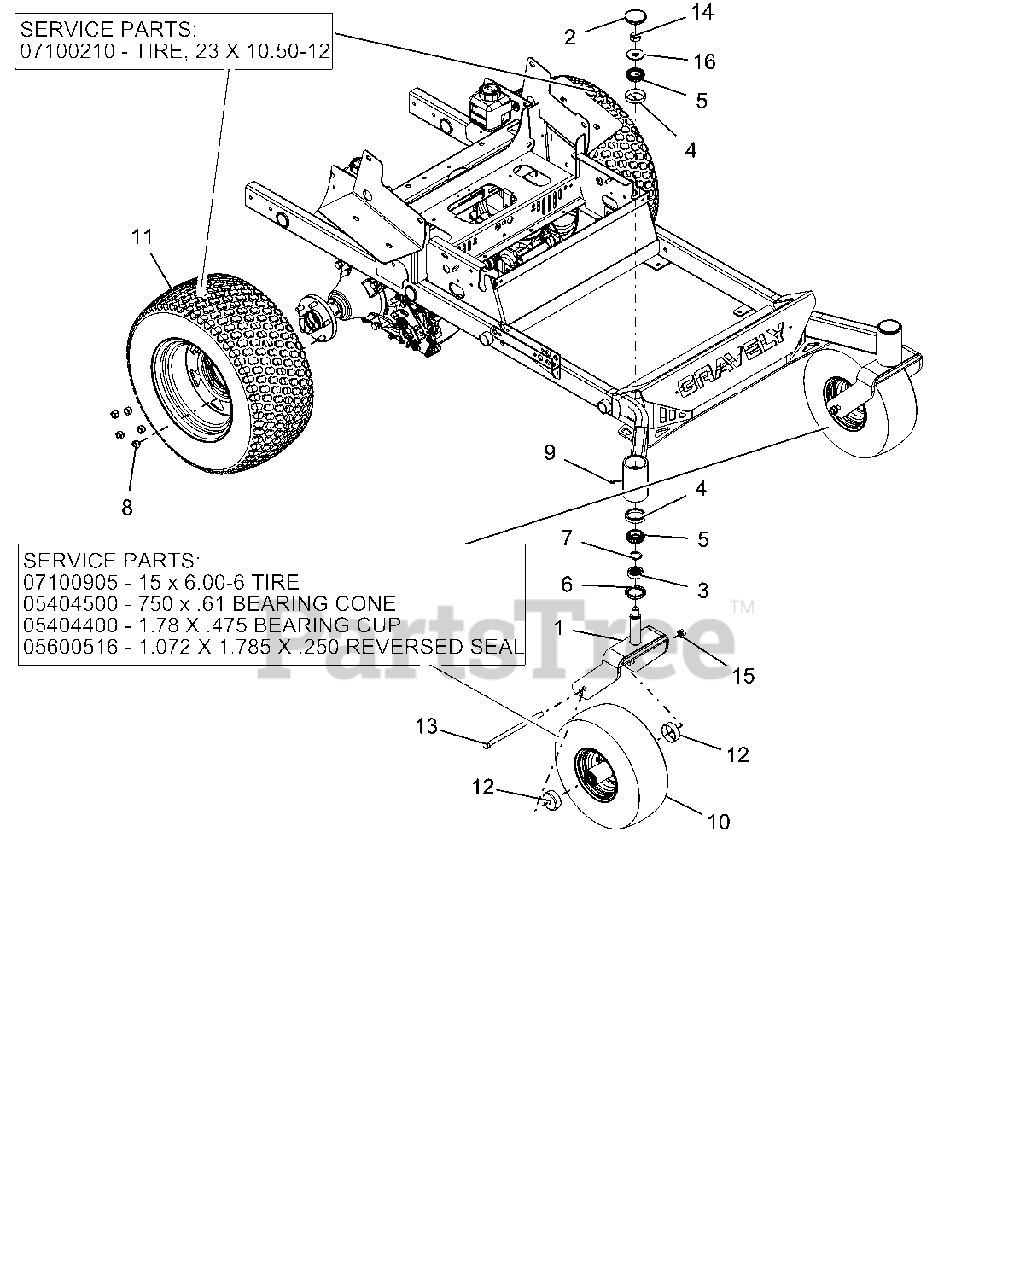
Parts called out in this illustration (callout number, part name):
1	WMT, CASTER FORK - RED
2	CAP, DUST
3	SPCR, FRONT CASTER FORK
4	BRG, CUP 2.328 X .465
5	BRG, CONE 1.250 X .660
6	SEAL, OIL 1.75 X 2.332 X .312
7	O-RING, .139 W X 1.234 ID
8	NUT, LUG .500-13
9	FITTING, .250-28 FLUSH MOUNT GREASE
10	ASSM TIRE\WHEEL, 15 X 6.00-6 SMOOTH
10	15 X 6.00-6 TIRE
10	750 X .61 BEARING CONE
10	1.78 X .475 BEARING CUP
10	1.072 X 1.785 X .250 REVERSED SEAL
11	ASSM TIRE\WHEEL, 23 X 10.50 - 12
11	TIRE, 23 X 10.50-12
12	SHIELD, WHEEL BEARING
13	BLT-HEX .50-13X9.00 GR5 YWZC
14	NUT-LK-TOP-JAM .75-16 YWZC
15	NUT, LK-TOP-FLG .50-13 YWZC
16	WSHR-FL-STL.812X2.00X.148YWZC
